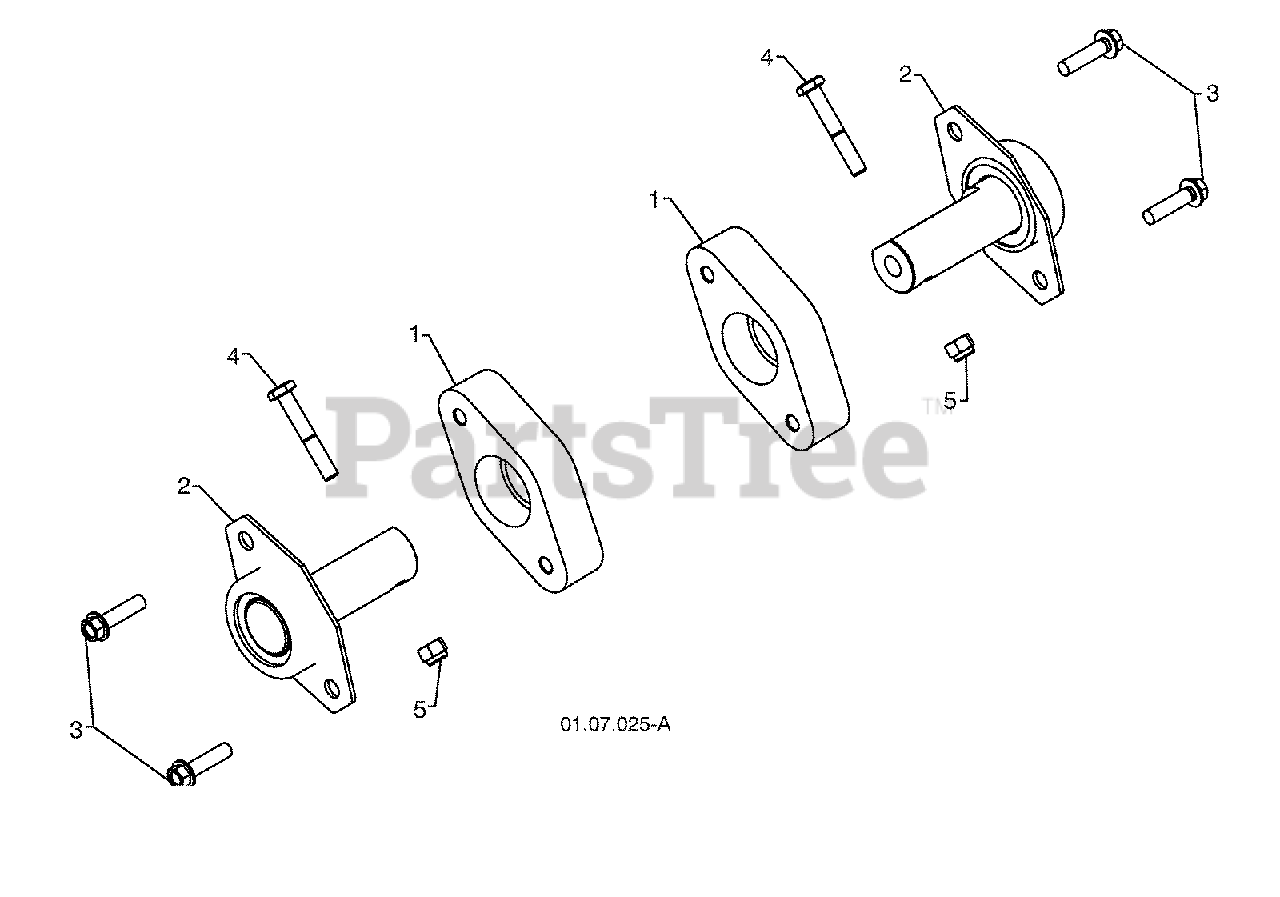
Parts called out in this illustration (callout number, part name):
1	PLASTIC RETAINER
2	AUGER BALL BEARING
3	SCREW 5/16-18 x 1.00
4	SCREW 1/4-20 x .625
5	NUT 1/4-20
